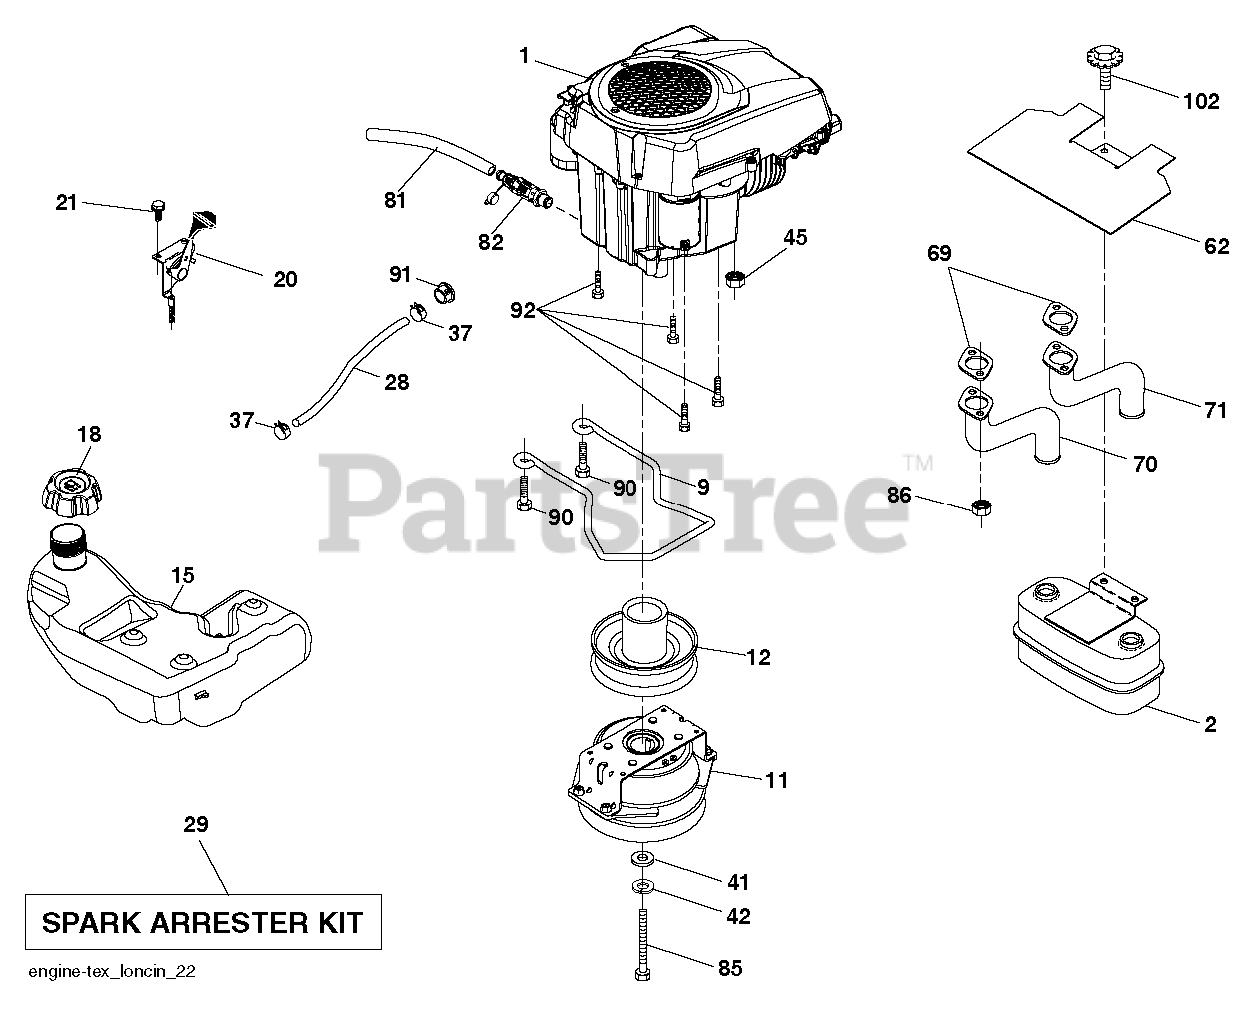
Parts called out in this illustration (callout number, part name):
2	MUFFLER.ASM.TWIN.MNTG.BRACKET
9	KEEPER.BELT.ENG.4.25"2.BLT.431
11	CLUTCH.OGURA.4.4PD.GT1.5-EH13V
12	PULLEY.ENGINE.TUFFTORQ
15	FUEL TANKS
15	Tanks
18	FUEL CAP
18	CAP ASSY FUEL 3" GRAY
20	CONTROL.TH/CK.COBRA.B&S.TWN.BK
28	LINE.FUEL.64"REAR.EMIS
29	KIT.SPARK ARRESTOR 794945 B&S
37	HOSE CLAMP
45	NUT HEXAGON WITH FLANGE, SERRA
62	SHIELD.HEAT.MUFFLER
81	TUBE, DRAIN OIL ASM.
82	VALUE.OIL.DRAIN
85	CLUTCH BOLT7/16-20X3.5 GR524HR
86	NUT.HEX.FLANGE.TOPLOCK
90	SCREW 3/8-16X1
91	BUSHING.1.375OD
92	SCREW 3/8-16X1
102	SCREW
